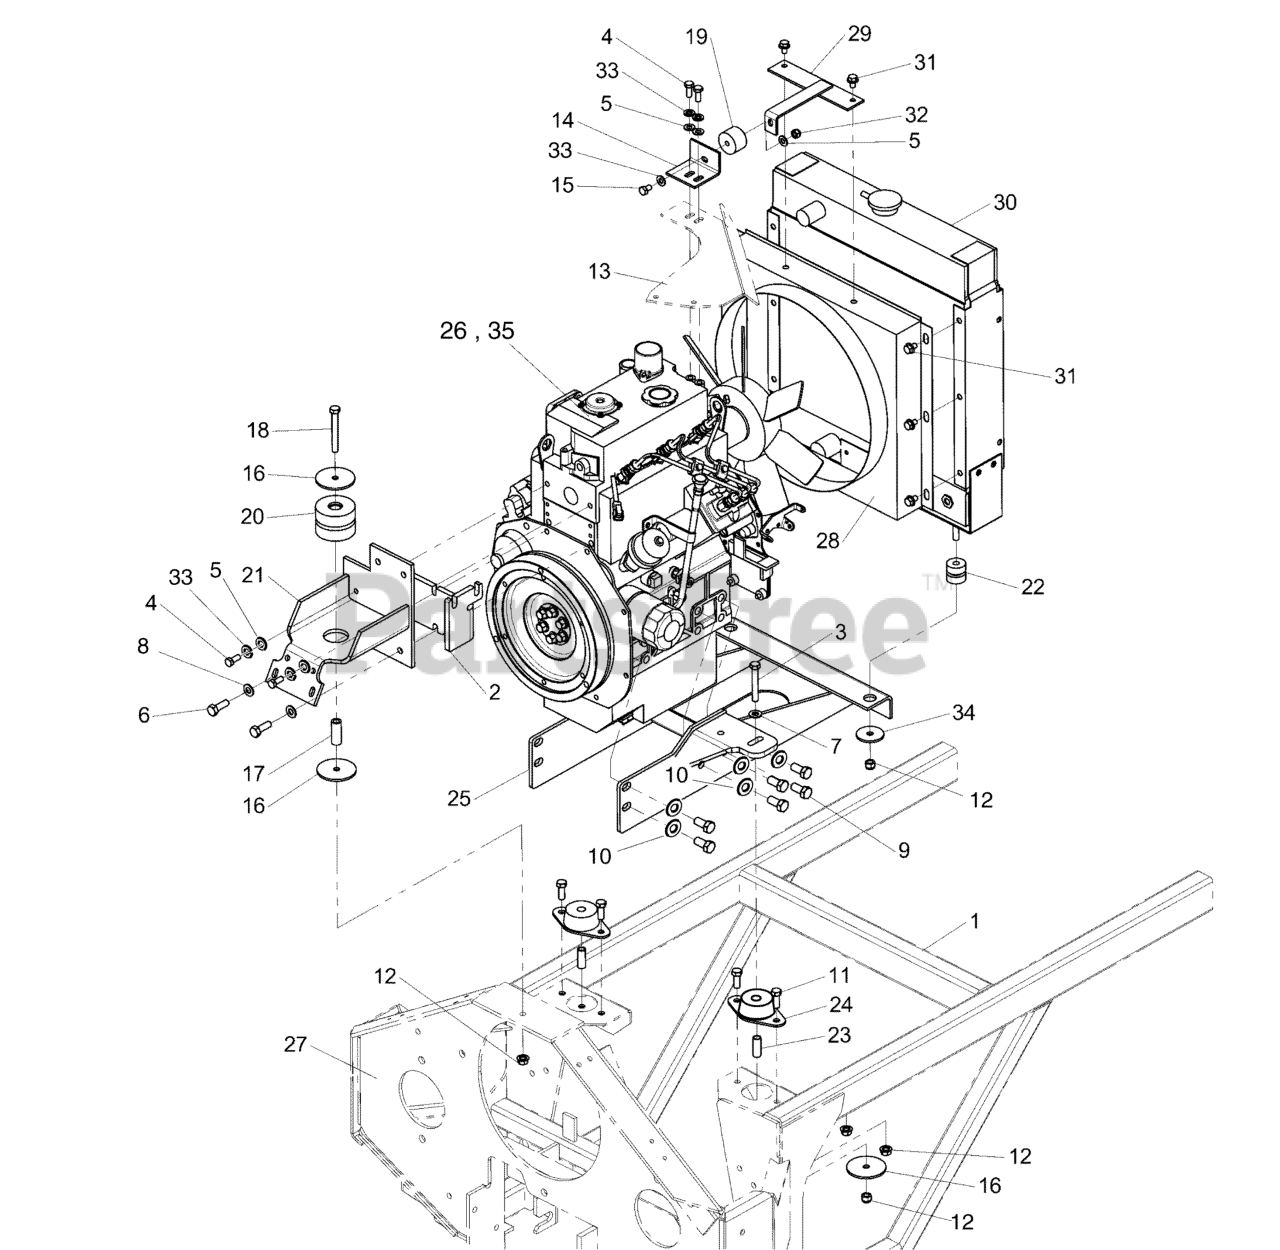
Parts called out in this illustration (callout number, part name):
1	MAIN FRAME
2	BRACKET, FUEL FILTER MOUNT
3	BOLT, 3/8-16 X 2-1/2" GD5 CZ
4	BOLT, M8-1.25 X 30MM, GD8.8 CZ
5	WASHER, 5/16" SAE
6	BOLT, M10-1.5 X 30MM GD8.8
7	WASHER, 3/8 SAE
8	WASHER, LOCK, 10MM
9	CAPSCREW-HEX HD, M12-1.75 X 25MM
10	WASHER, 1/2 SAE
11	BOLT, 3/8-16 X 1" GD5 CZ
12	NUT, 3/8-16 HEX NYLOCK FLANGE
13	AIR FILTER PLATE
14	MOUNT, RADIATOR, TOP ISO
15	BOLT, 5/16-18 X 3/4 GD5
16	WASHER, .39 X 2.50 X .125
17	SPACER, .38 X .62 X 1.62
18	BOLT, 3/8-16 X 3" GD5 CZ
19	ISO-MOUNT, TOP, DIESEL
20	ISO-MOUNT, REAR, DIESEL (2 piece)
21	WELD, REAR ISO MOUNT
22	ISO-MOUNT, BOTTOM, DIESEL (2 piece)
23	SPACER, .38 X .50 X 1.33
24	ISO-MOUNT, ENGINE
25	WELD RADIATOR SUPPORT
27	PUMP PLATE
28	BAFFLE, RADIATOR
29	WELD, UPPER RADIATOR
30	RADIATOR, CAT DIESEL 3011C
31	BOLT, 5/16-18 X 1/2" FLANGE, SPEC
32	NUT, 5/16-18 HEX NYLOCK FLANGE
33	WASHER, 5/16 LOCK CZ
34	WASHER, .41 X 1.75 X .14
36	TIE,SELF-LOCKING, 24"
